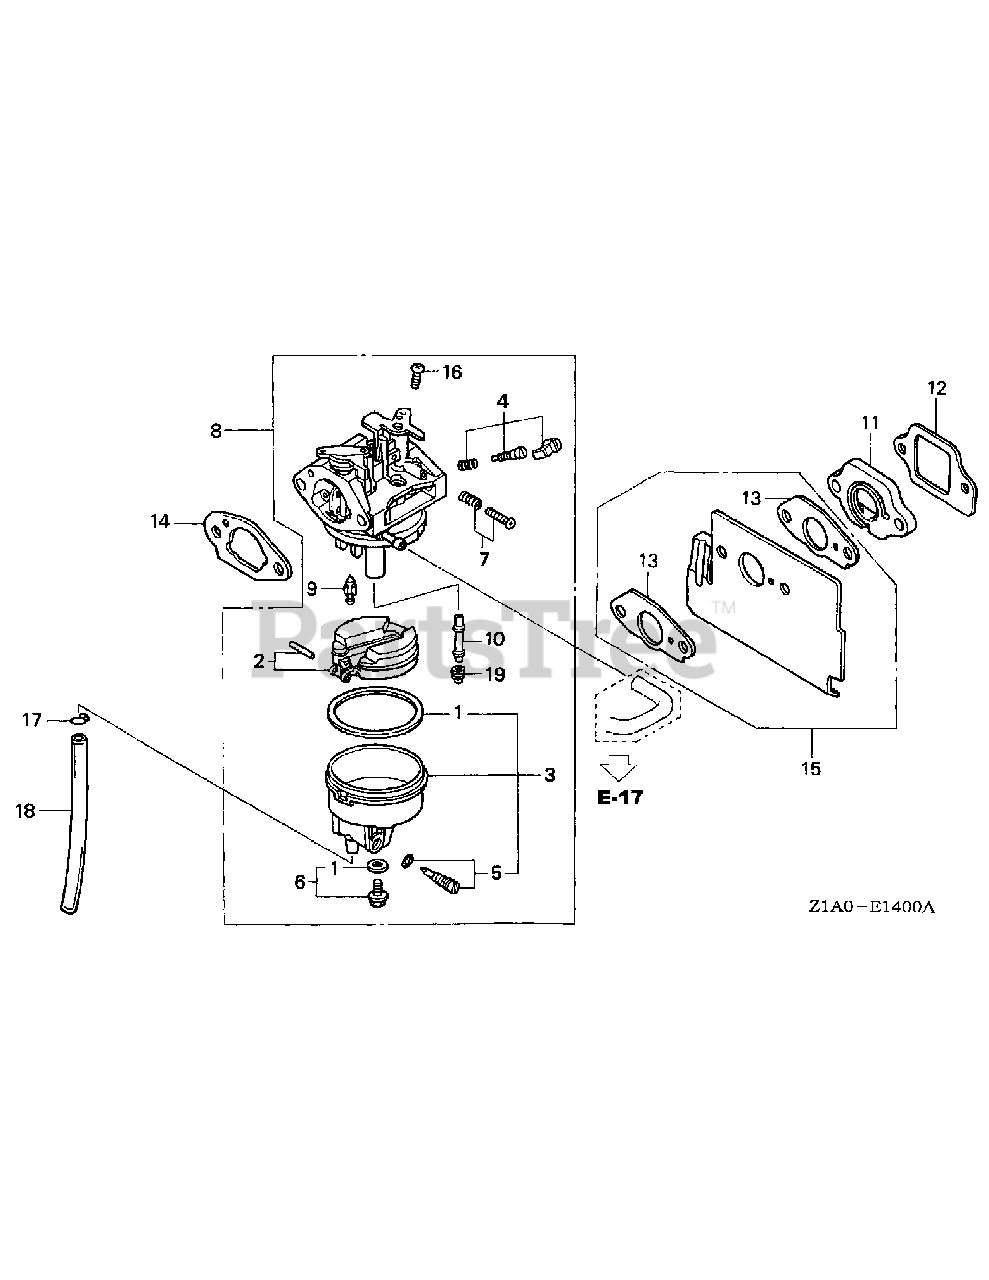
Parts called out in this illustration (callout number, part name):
1	Gasket Set
3	Chamber Set, Float
5	Screw Set, Drain
6	Screw Set
7	Screw Set (Throttle Stop)
8	Carburetor Assy. (Bb61K A)
9	Valve Comp., Float
10	Nozzle, Main
11	Insulator, Carburetor
12	Gasket, Insulator
13	Gasket, Carburetor
14	Gasket, Carburetor
15	Guide Comp., Air
16	Screw, Pan, 5X6
17	Clip, Tube (B6.5)
18	Tube, Vinyl, 4X7X150
19	Jet, Main, #62
19	Jet, Main, #65
19	Jet, Main, #68
